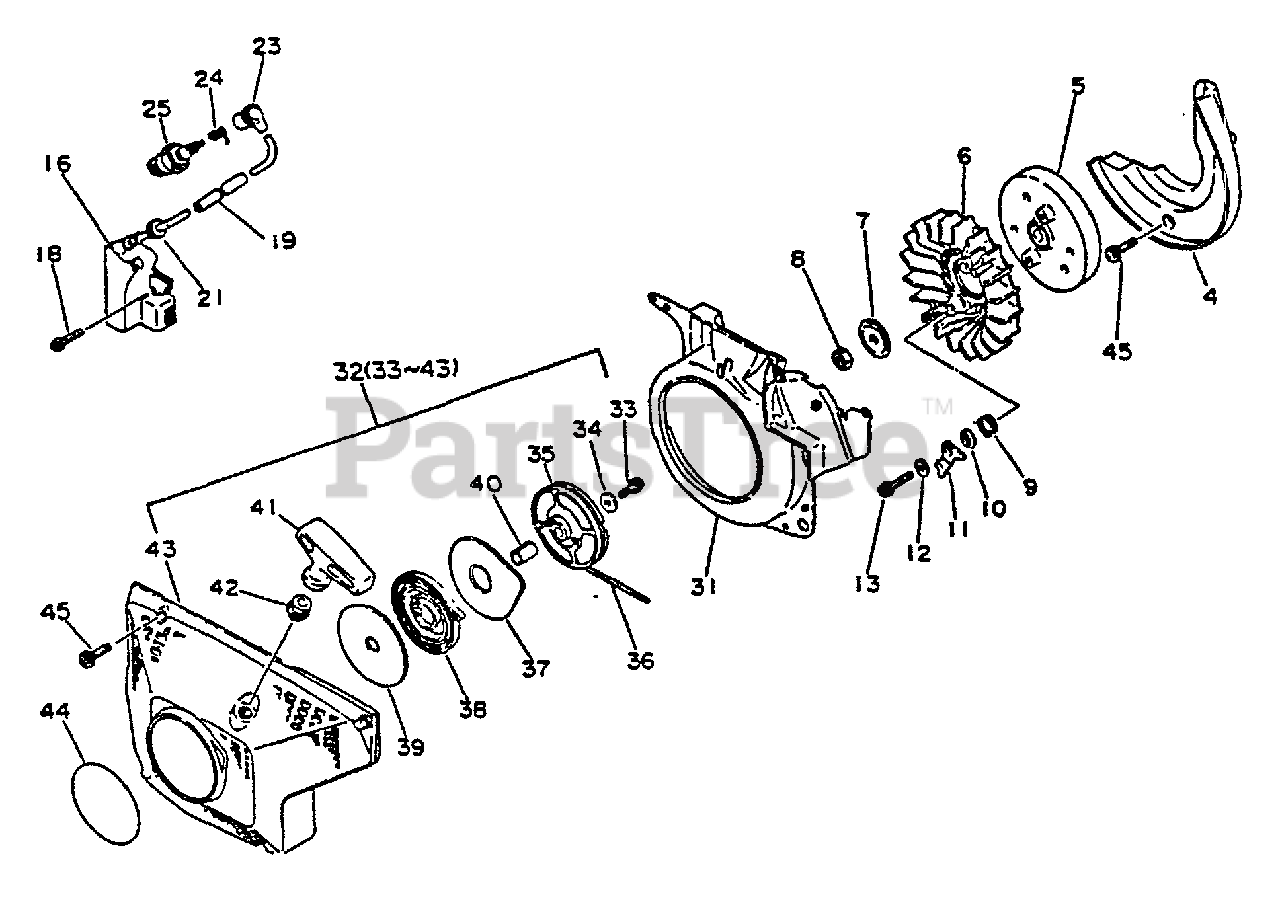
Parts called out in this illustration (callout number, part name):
4	SHIELD, FAN
5	FLYWHEEL
6	FAN
7	WASHER - CUP
9	SPRING, RETURN
10	SPACER
11	PAWL, STARTER
12	WASHER - 5
13	SCREW - 5X30
16	COIL, IGNITION
18	SCREW - 4X20
23	CAP, SPARK PLUG
24	TERMINAL, SPARK PLUG CAP
25	SPARK PLUG -- CJ-6Y
31	SHIELD, FAN
32	STARTER ASSY
33	SCREW - 5X14
34	WASHER - 5
35	REEL, ROPE
36	ROPE, STARTER - 4X950
37	PLATE, STARTER
38	SPRING, REWIND
39	PLATE, STARTER
41	GRIP, STARTER
42	GUIDE, ROPE
43	CASE, STARTER
44	LABEL - ECHO
45	SCREW - 5X20
